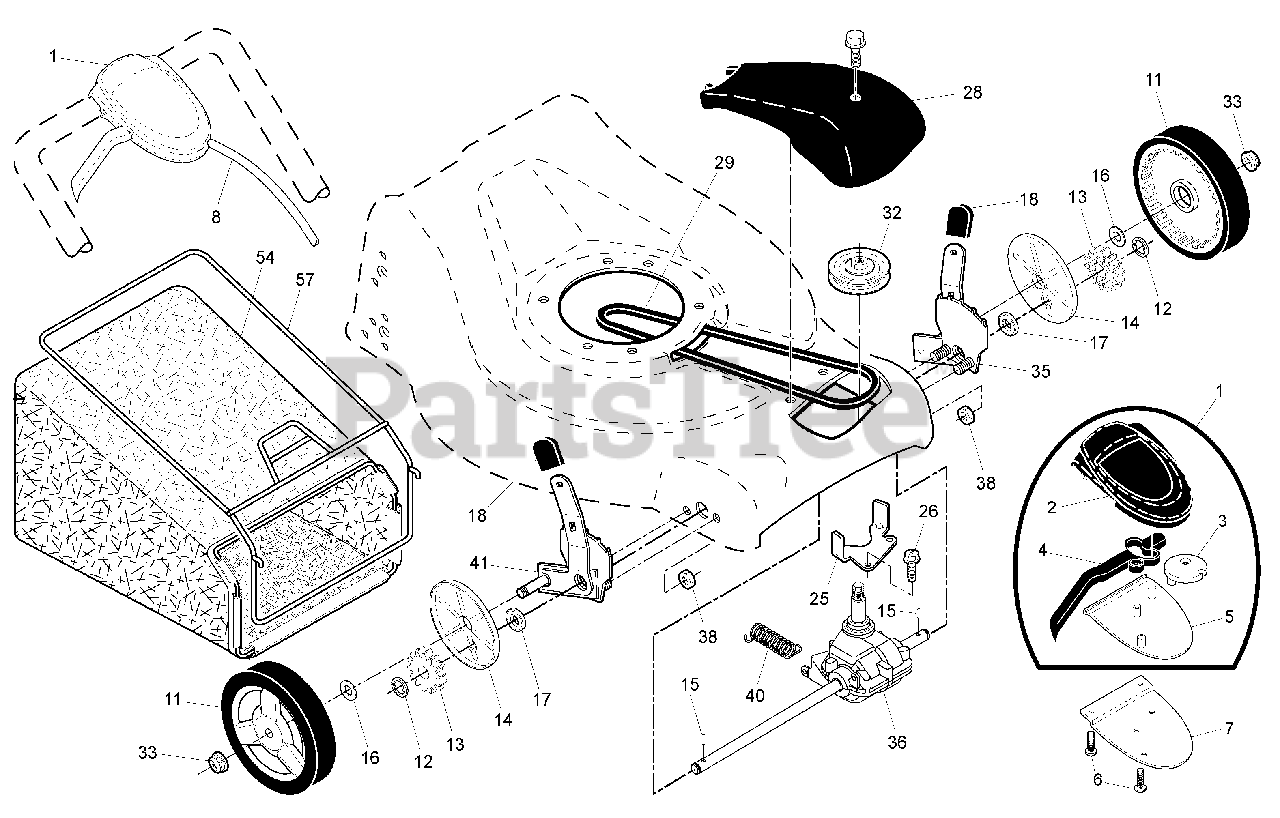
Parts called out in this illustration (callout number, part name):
1	Drive Control Assembly
2	Cover, Drive Control, Upper
4	Lever, Drive Control
5	Cover, Drive Control, Lower
7	Mounting Bracket, Drive Control
8	Cable, Drive
11	Wheel & Tire Assembly
14	Dust Cover
15	Pawl, Drive
16	Washer 1/2 x 1-1/2 x .134
17	Bearing Assembly, Wheel Adjuster
18	Selector Knob
25	Belt Keeper
26	Screw, Hi-Lo Thread
28	Drive Cover Assembly
32	Drive Pulley
33	Locknut, Hex
35	Kit, Wheel Adjuster, LH
36	Gearcase Assembly, Complete
38	Locknut, Hex 1/4-20
41	Kit, Wheel Adjuster, RH
54	Grassbag Assembly
57	Frame, Grassbag
